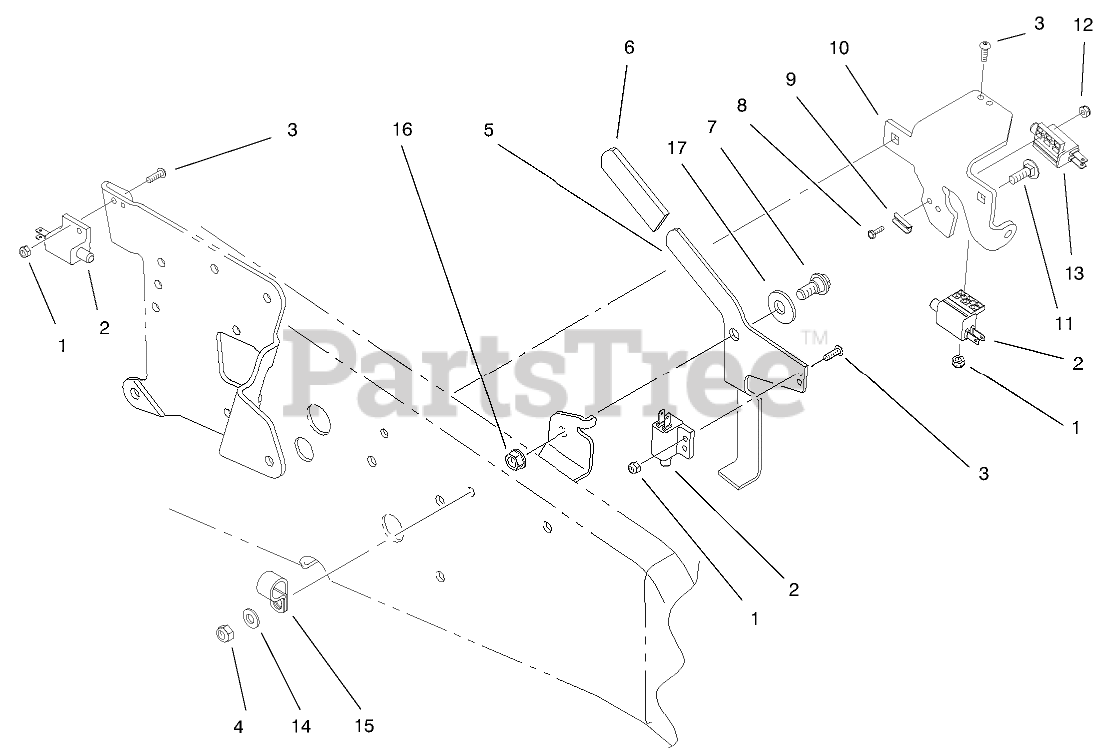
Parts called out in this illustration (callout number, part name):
1	NUT-LOCK, NI
2	SWITCH-POLE, SINGLE
3	SCREW-HSH
4	NUT-LOCK, NI
5	LATCH-BRAKE, PARKING
7	BOLT-SHOULDER
8	SCREW-SHH
9	RETAINER-SCREW
10	BRACKET-SWITCH
11	SCREW-CARR
12	NUT-LOCK
13	SWITCH-POLE, SINGLE
14	WASHER-PLAIN
15	CLAMP - R
17	WASHER
